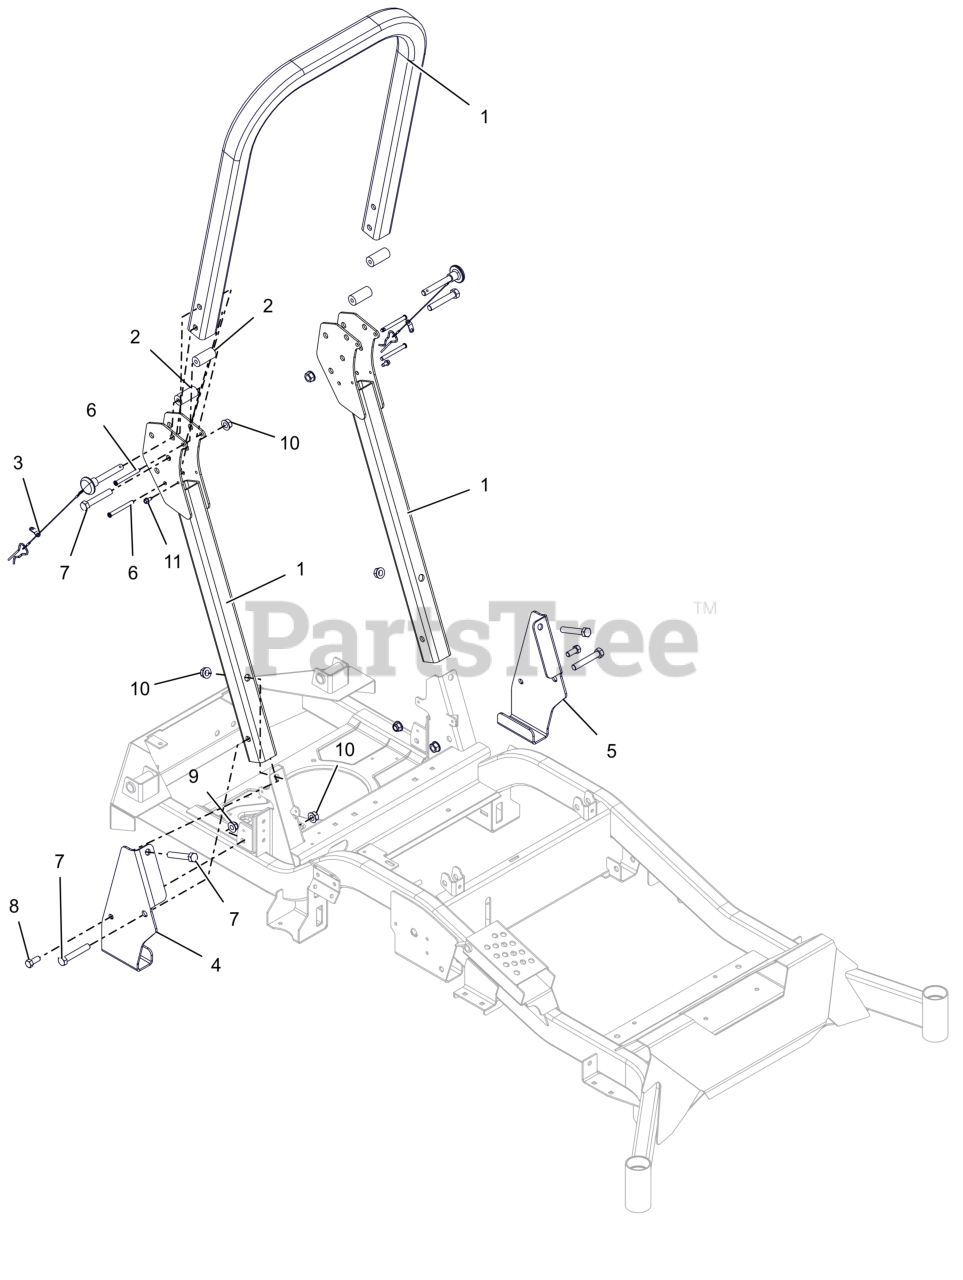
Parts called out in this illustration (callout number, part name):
1	ROPS,PROTURN Z REPLACEMENT-TALL
2	BUMPER, ROPS ANTI-VIBRATION
3	PIN, ROPS W/LANYARD
4	BRKT, ROPS SUPPORT - RH
5	BRKT, ROPS SUPPORT -LH
6	PIN, SLIC .312 X 2.57
7	BLT, HEX .50-13X3.00 G5 ZCC
8	BLT, HEX .44-14X1.00 G5 ZCC
9	NUT, LK-NYL-FLG .44-14 GR5 ZC120
10	NUT-LK-CTR-FLG .500-13 GG ZCC
11	SCR-TAP .25-20X.50 HWH ZCC
